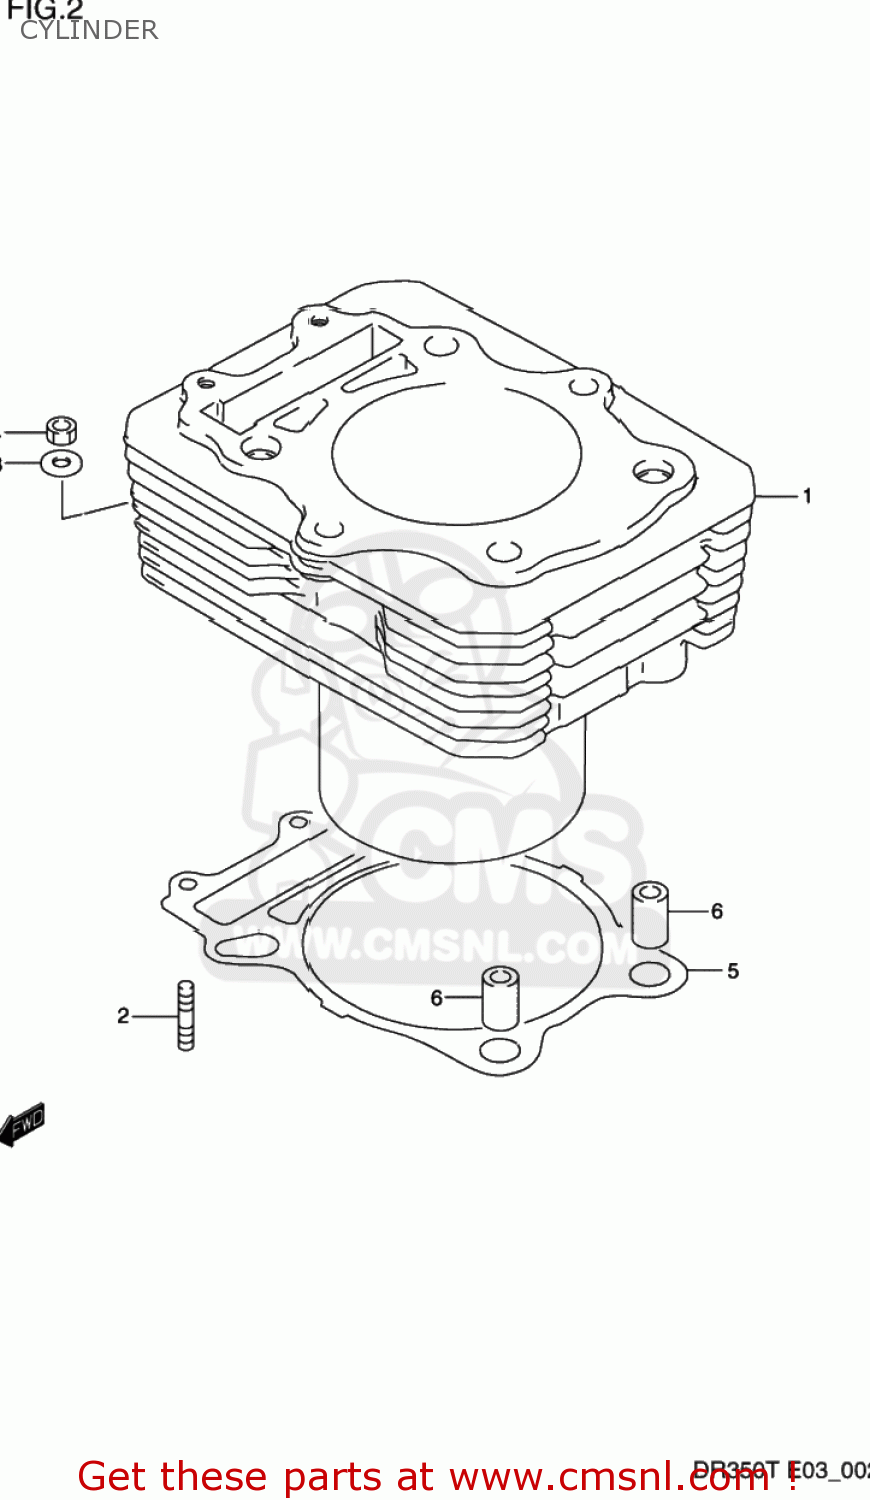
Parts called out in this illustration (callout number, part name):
1	CYLINDER
2	STUD 6X20
3	WASHER
4	NUT
5	GASKET,CYLINDER (NAS)
6	PIN
